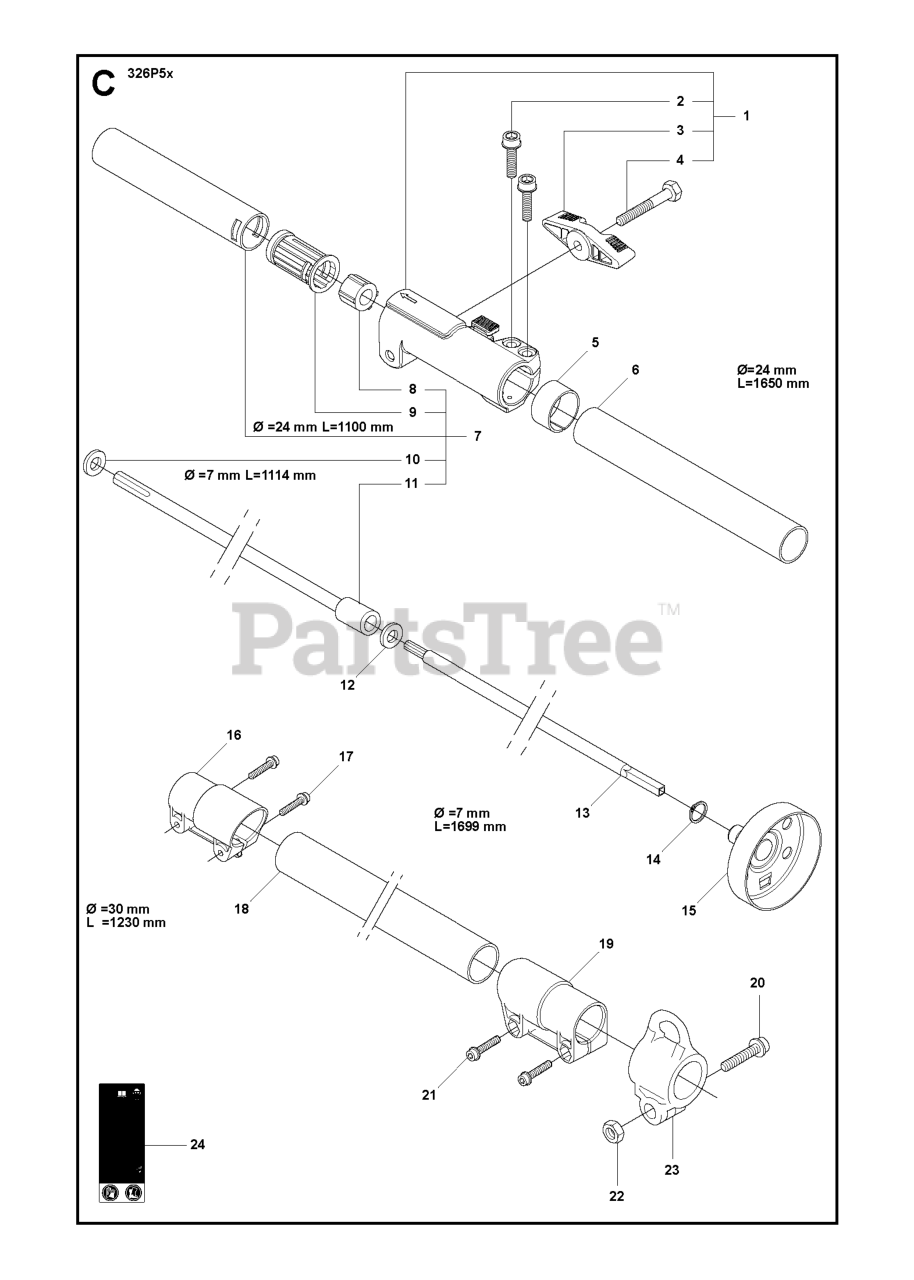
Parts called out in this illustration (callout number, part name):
1	CLAMPING SLEEVE
2	SCREW
6	TUBE
7	TUBE
8	BUSHING
9	PLUG
11	SHAFT
13	DRIVE SHAFT
14	RETAINING RING SGA 10
15	CLUTCH DRUM
16	LOCKING SLEEVE
18	PIPE
19	LOCKING SLEEVE
20	SCREW
23	HARNESS HOLDER
